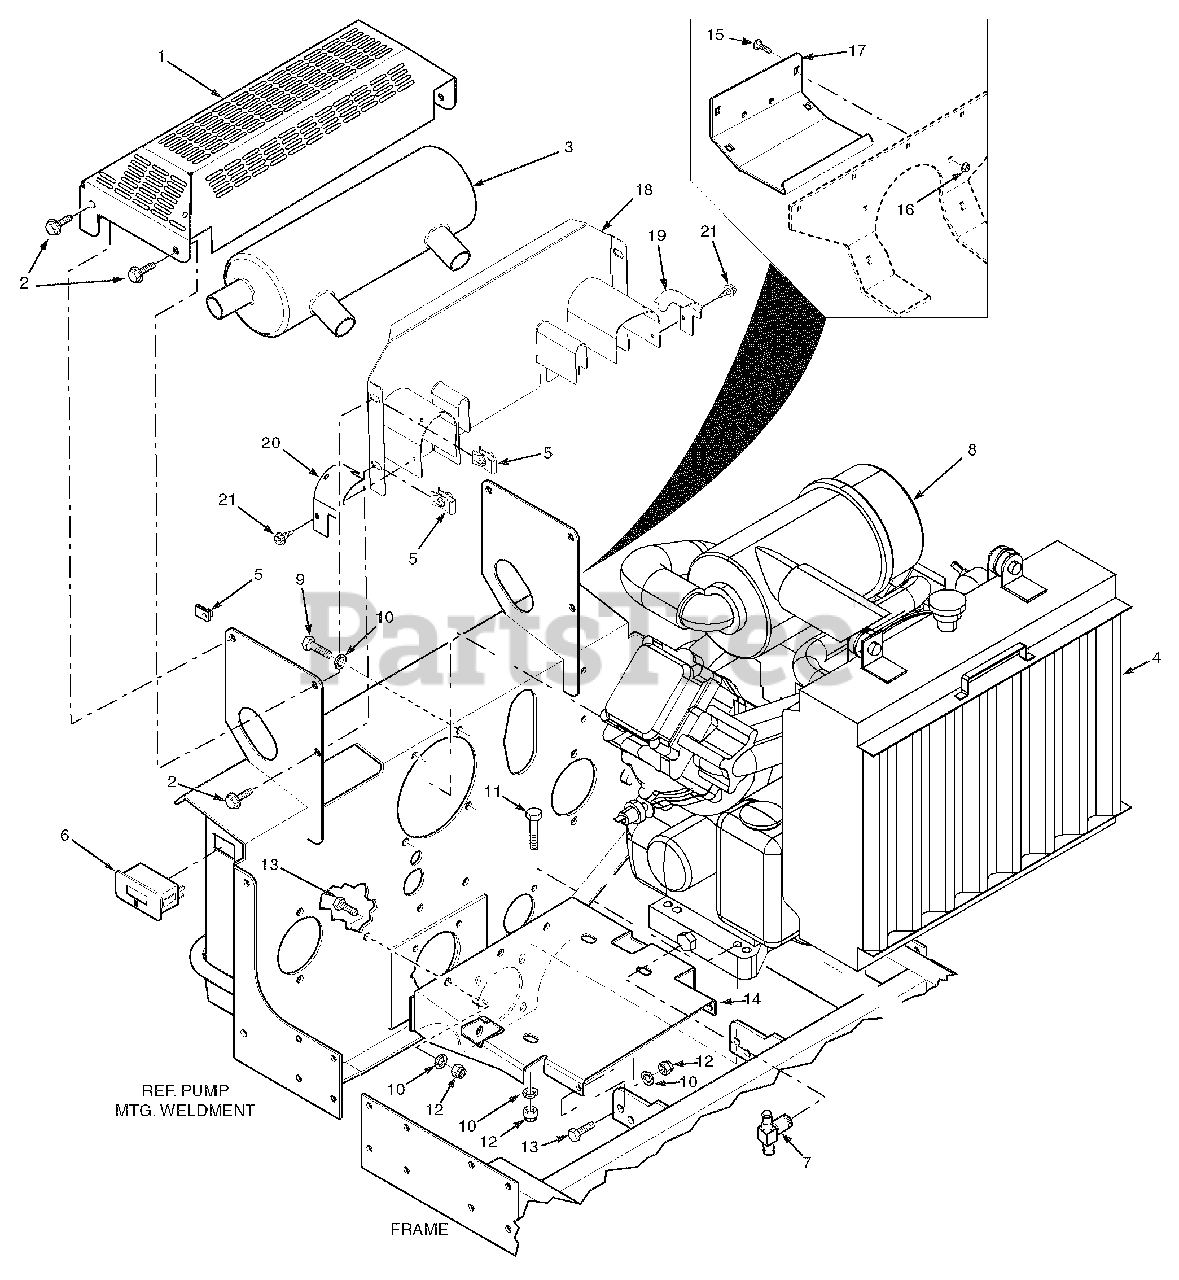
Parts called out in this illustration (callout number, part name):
1	Muffler Guard
2	Screw, Hex Serrated Flange 1/4-20 x 3/4"
3	Muffler, Briggs & Stratton
4	Screen Weldment, Radiator
5	U-Nut, 1/4-20
6	Hour Meter
7	Oil Drain
8	Engine, Briggs & Stratton 35HP V-Twin Liquid Cooled
9	Bolt, M10-1.50 x 25 Grade 8.8
10	Lockwasher, 3/8" Spring
11	Bolt, Hex Head 3/8-16 x 1-3/4"
12	Nut, Hex Elastic Stop 3/8-16
13	Bolt, Hex Head 3/8-16 x 1-1/4"
14	Plate, Engine Mounting
15	Bolt, Carriage 5/16-18 x 3/4"
16	Nut, Hex Serrated Flange 5/16-18
17	Rear Cover
18	Heatshield Weldment, Muffler
19	Heatshield Ext., LH
20	Heatshield Ext., RH
21	Screw, #10 x 1/2" Self Tap
